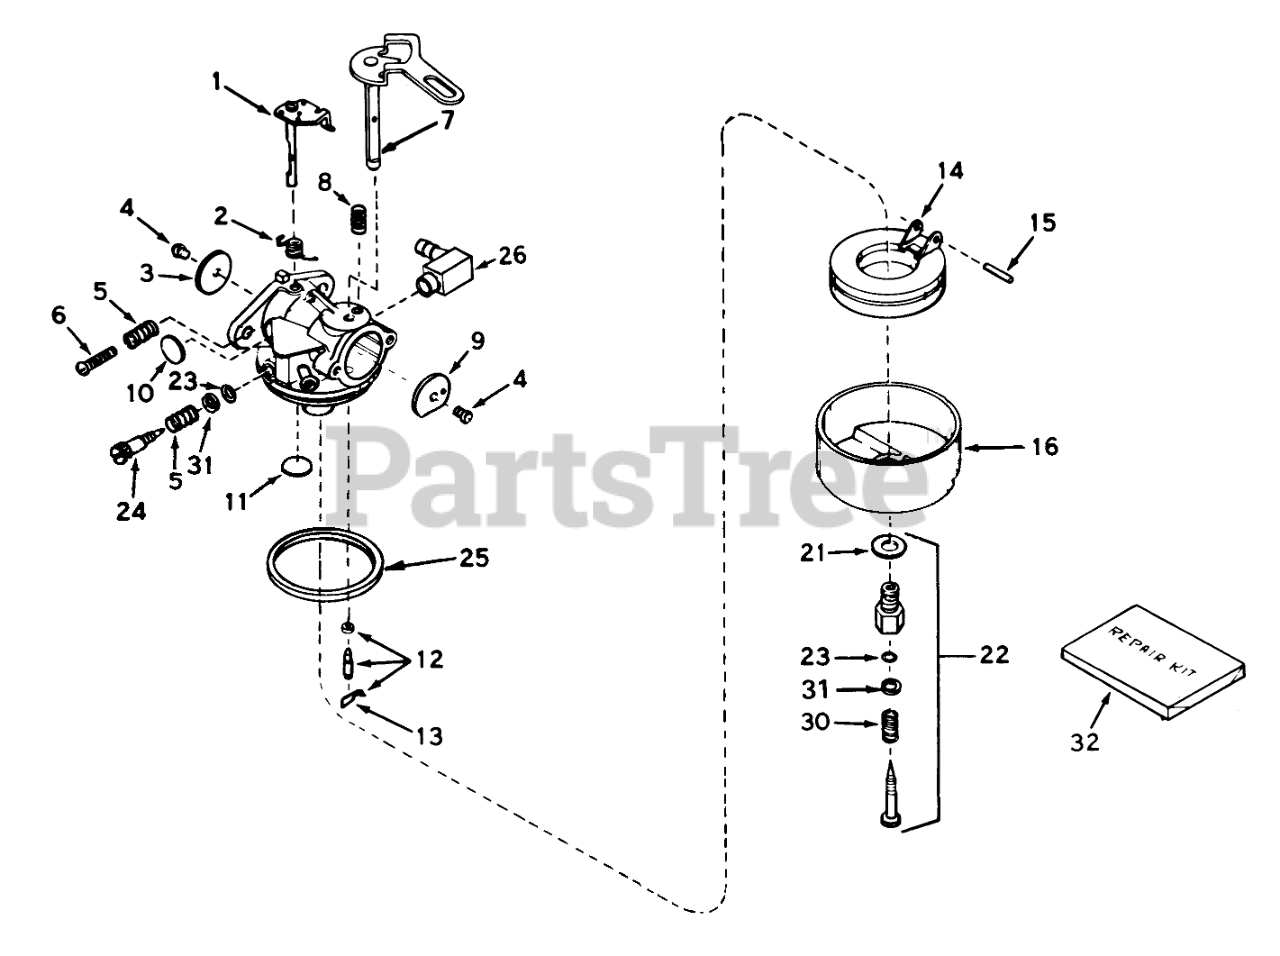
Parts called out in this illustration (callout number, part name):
1	Throttle Shaft and Lever ASM
2	Spring, Return
3	Shutter-Throttle
4	Screw-Shutter
5	Spring-Tension
6	Screw-Throttle Crack Screw / Idle Speed
7	Choke Shaft and Lever Asm
8	Spring-Positioning, Choke
9	Shutter-choke
10	Plug-Welch, Idle Mixture Well
11	Plug-Welch, Atmospheric Vent
12	Inlet Needle, Seat & Clip Assy. (Incl. Ref. #13)
13	Clip-Spring
14	Float
15	Shaft-Float
16	Bowl-Float (no drain)
21	Washer-Bowl Nut
22	Adjustment Screw Assy., Main (Incl. Ref. #21, 23, 30 & 31)
23	"O"Ring
24	Screw, Idle Adj.
25	O Ring-Bowl, Float
26	Fitting-Fuel
32	Kit-Repair
